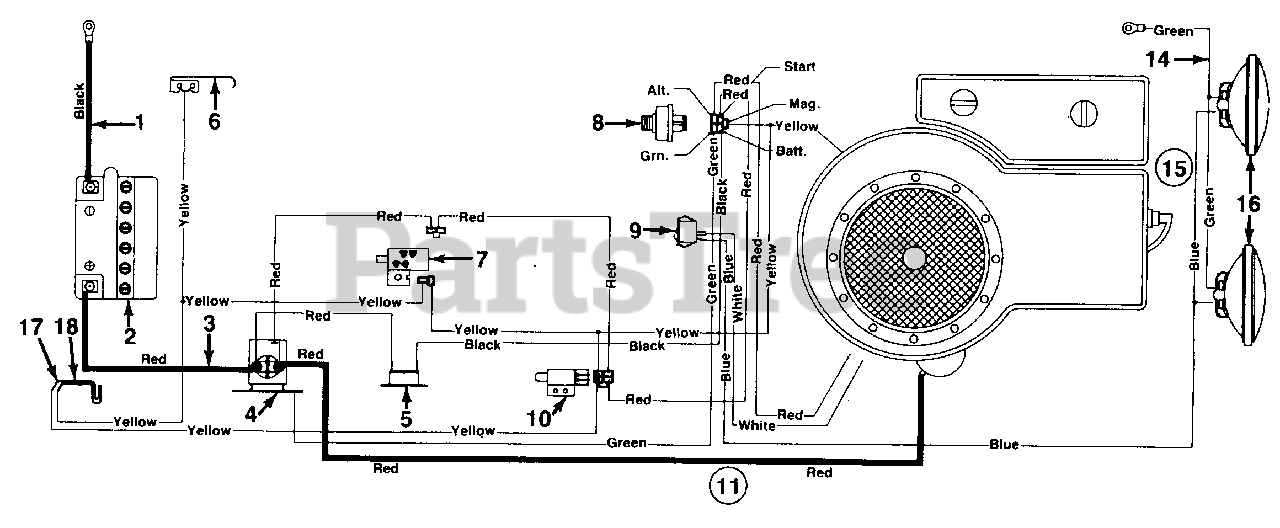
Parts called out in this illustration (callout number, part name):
2	Battery
3	Electric Wire-8.0" Lg.
4	Solenoid
5	Circuit Breaker
6	Spring Switch
7	Safety Switch
8	Ignition Switch
9	Light Switch
10	Safety Switch
15	Headlight Harness
16	Headlight
17	Safety Switch
18	Safety Switch
